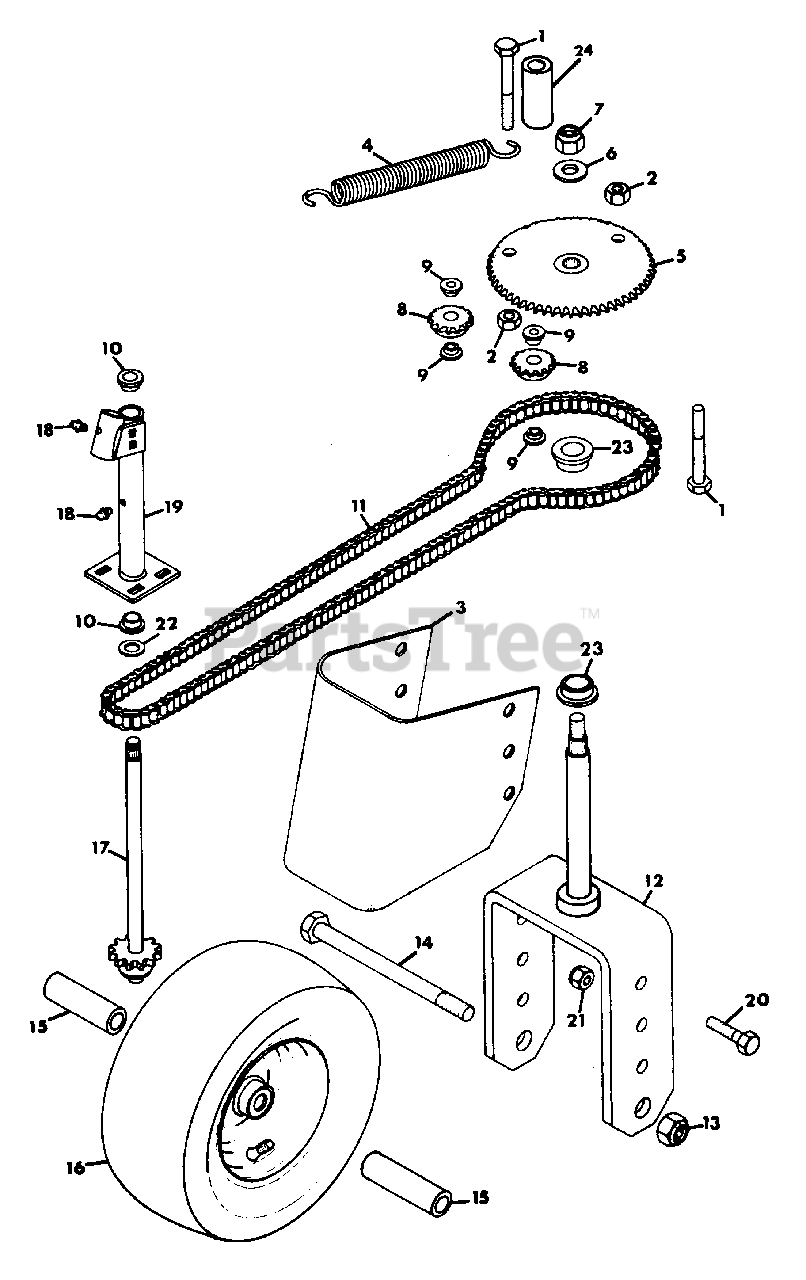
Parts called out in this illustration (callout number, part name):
1	BOLT, HEX 1/2-13X3.25
2	NUT, HEX 1/2-14
3	SHIELD, GRASS
4	SPRING
5	SPROCKET, 57-T #40
6	WASHER, FLAT .656X1.312X.095
7	NUT, LOCK 5/8-11
8	SPROCKET, DRIVE
9	BUSHING
10	BEARING, FLANGED
11	CHAIN, #40
12	WELDMENT, WHEEL FORK
13	NUT, LOCK 3/4
14	AXLE
15	SPACER, WHEEL
16	ASSEMBLY, WHEEL & TIRE 16X7.50-8
17	SHAFT, STEERING
18	FITTING, LUBE 1/4-28
19	TUBE, STEERING
20	BOLT, HEX 1/2-13X1.25
21	NUT, LOCK 1/2-13
22	BEARING, THRUST RACE
23	BEARING, FLANGED 24
24	SPACER, .850X.546X2.18
